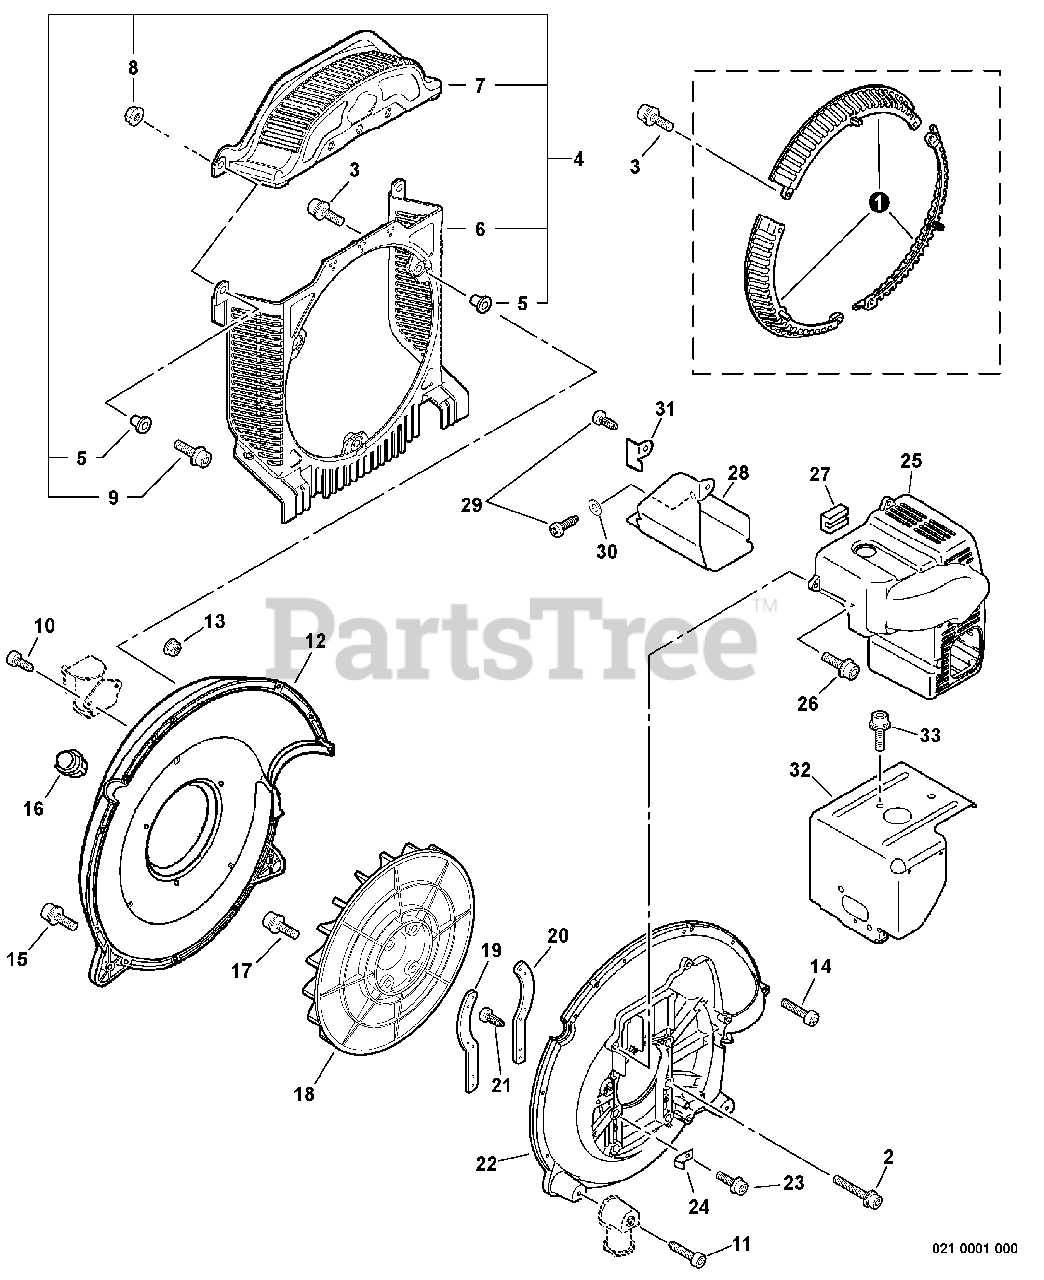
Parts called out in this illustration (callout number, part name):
1	GUARD, DEBRIS
2	SCREW - 6X35
3	SCREW - 5X20 -- TAPPING
4	DEBRIS GUARD KIT
6	GUARD, DEBRIS - LOWER
7	GUARD, DEBRIS - UPPER
8	LOCKNUT - 5
9	SCREW - 5X20
10	SCREW - 5X16
11	SCREW - 5X16
12	COVER, FAN - INNER
13	NUT - 5 -- FLANGE
14	SCREW - 5X60
15	SCREW - 5X20 -- TAPPING
17	SCREW - 5X30
19	PLATE - LEFT
20	PLATE - RIGHT
21	SCREW - 5X14
22	COVER, FAN - OUTER
23	SCREW - 5X16
25	COVER, ENGINE
26	SCREW - 5X20 -- TAPPING
27	CUSHION
28	SHIELD, EXHAUST
29	SCREW - 5X10
30	WASHER - 5
31	BRACKET, SHIELD
32	SHIELD, CYLINDER - INTAKE
33	SCREW - 5X8
